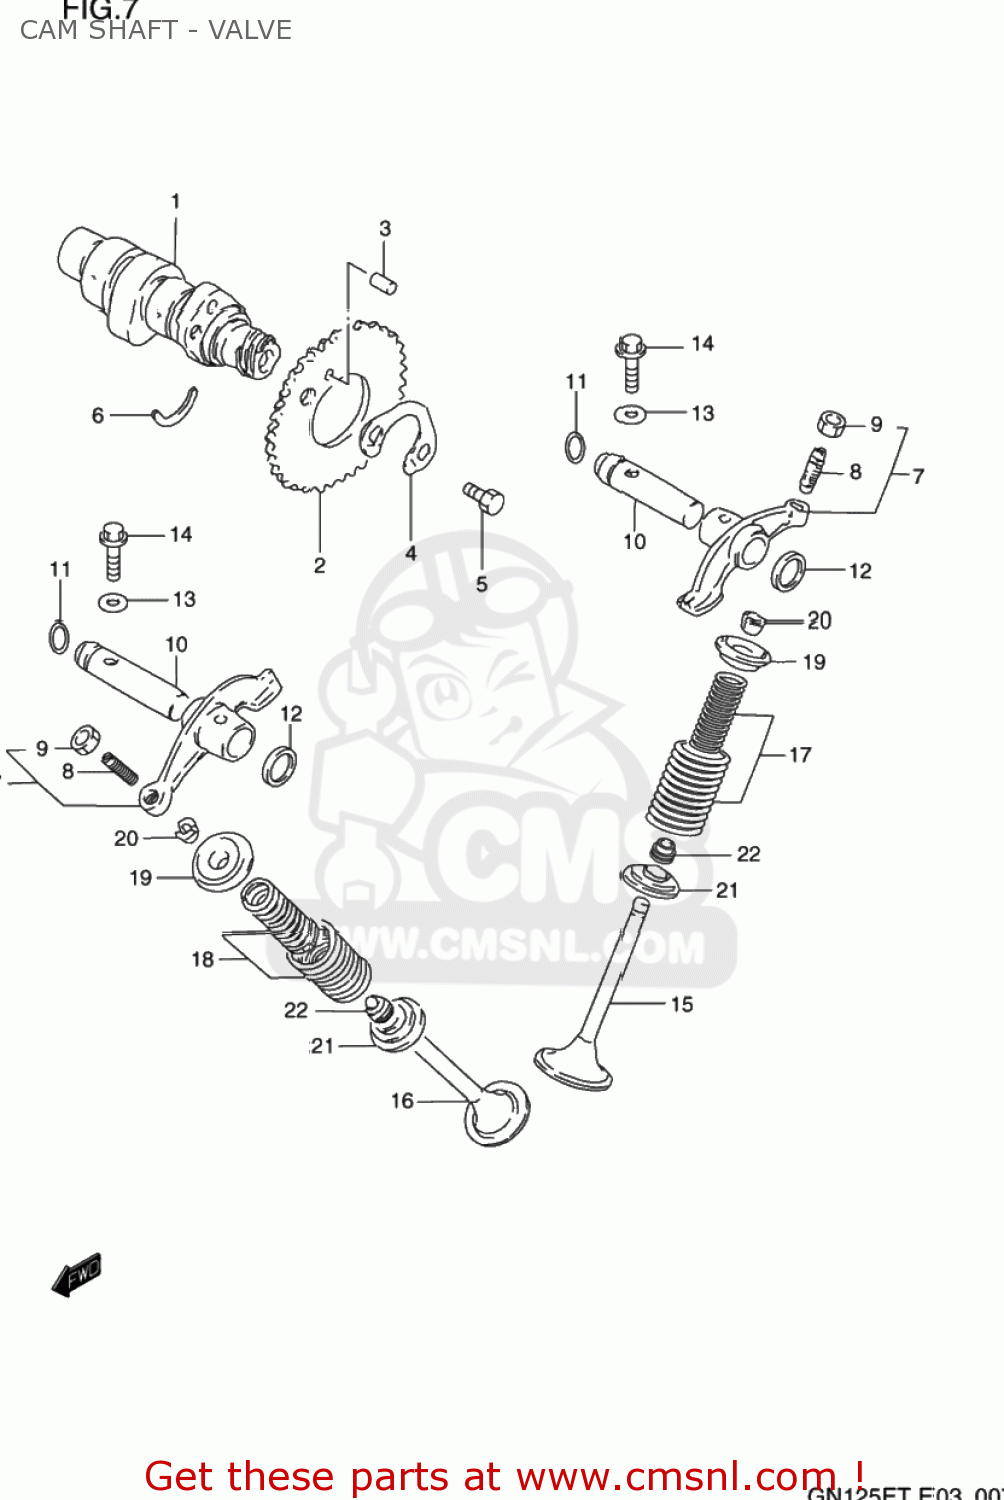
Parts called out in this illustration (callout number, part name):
1	CAMSHAFT
2	SPROCKET,CAMSHAFT
3	PIN(5X8)
4	WASHER,SPROCKET
5	BOLT(6X10.5)
6	C RING
7	ARM,VALVE ROCKER
8	SCREW,TAPPET ADJUSTING
9	NUT,ADJUSTING SCREW
10	SHAFT,VALVE ROCKET
11	O RING(D:1.9,ID:8.6)
12	WASHER
13	GASKET(5.8X13X1.2) (NAS)
14	BOLT
15	VALVE,INTAKE
16	VALVE,EXHAUST
17	SPRING SET,VALVE
18	SPRING SET,VALVE
19	RETAINER,VALVE SPRING
20	COTTER,VALVE
21	SEAT,VALVE SPRING
22	OIL SEAL
